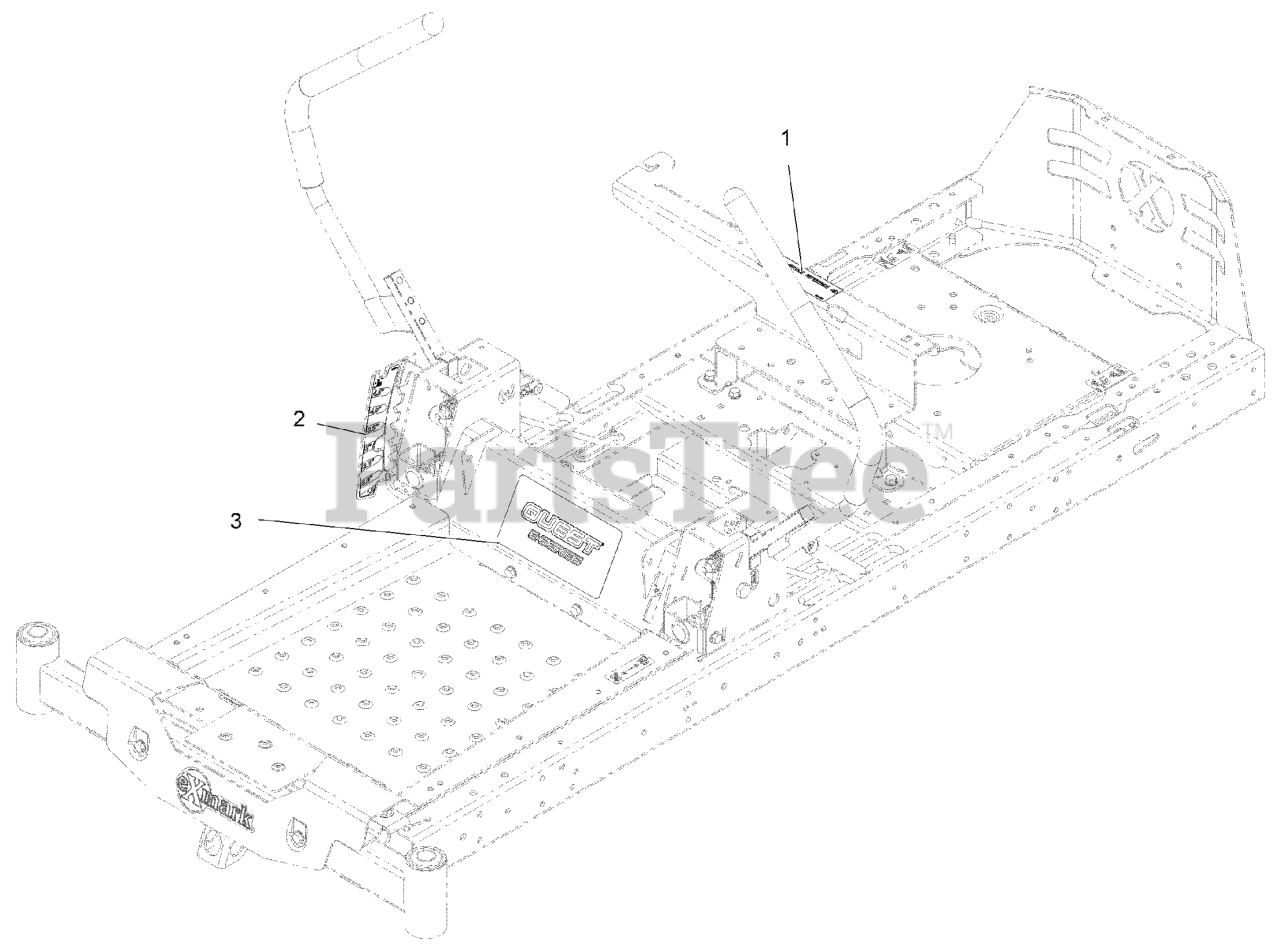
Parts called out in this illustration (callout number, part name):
1	DECAL-SERVICE, CE
2	DECAL-HOC
3	DECAL, QUEST E SERIES
